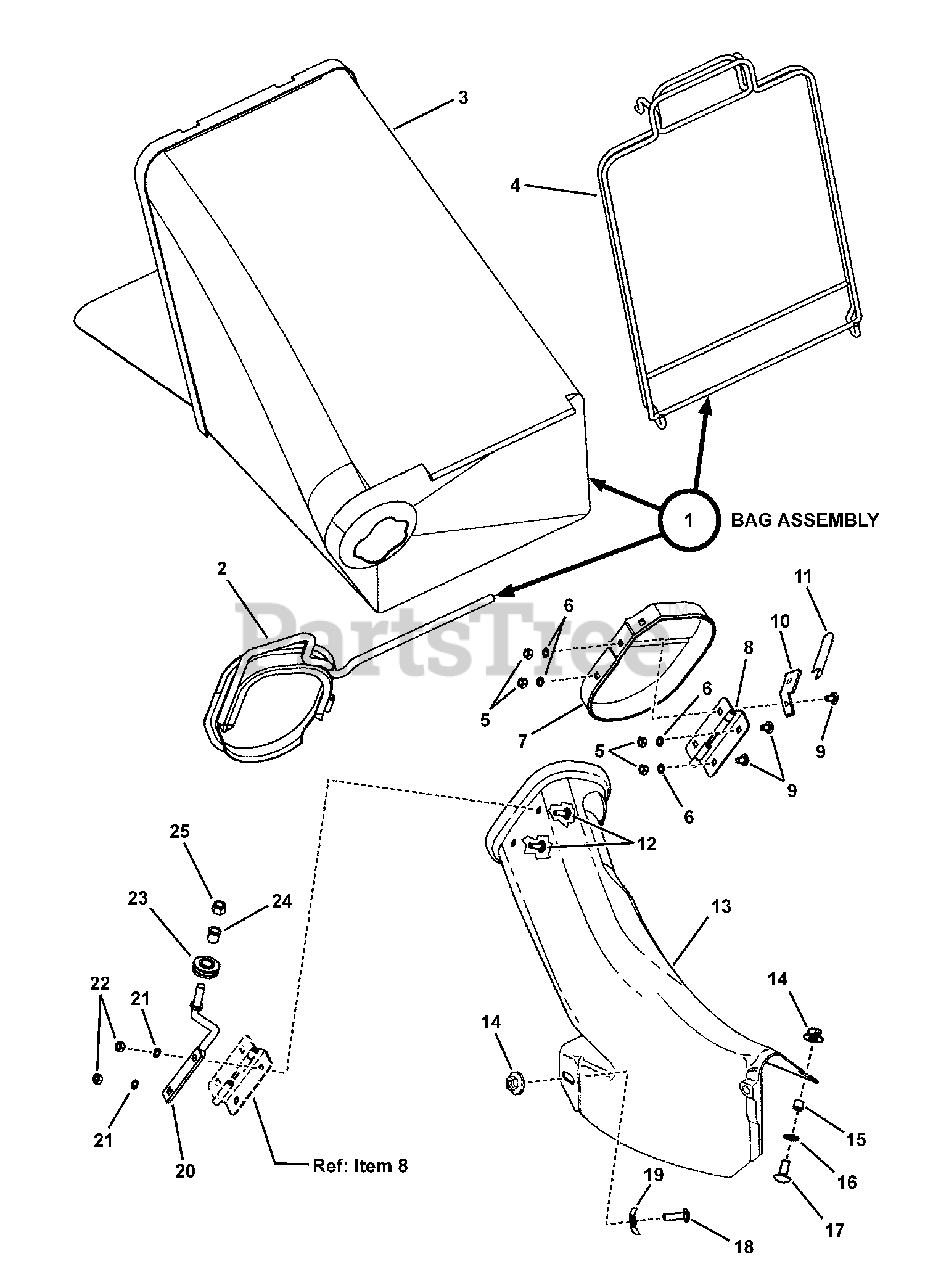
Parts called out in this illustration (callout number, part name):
1	BAG ASSEMBLY (Door)
2	CONNECTOR, Bag
3	GRASS BAG (Door w/silver letters)
4	ASSEMBLY, Bag Wire (12") 21S
5	NUT, 1/4-20 Hex
6	WASHER, 1/4" Internal Tooth Lock
7	COVER, Bag Adapter
8	HINGE, Chute Cover
9	BOLT, 1/4-20 x 5/8" Flat Head Square Neck, GR 5
10	STOP, Cover
11	TRIM, Moulding
12	BOLT, 1/4-20 x 3/4" Short Square Neck Carriage, GR 5
13	ADAPTER, Bag 21
14	NUT, 5/16-18 Large Flange Hex Center Lock
15	SPACER, .316 x .375 x .300/.310
16	BOLT RETAINER, 5/16- Black
17	BOLT, 5/16-18 x 3/4" Short Square Neck Carriage, GR 5
18	SCREW, 5/16-18 x 5/8" Cross Recess Pan Head
19	NUT, 5/16-18 Speed
20	ROD, Rope Pulley
21	LOCKWASHER, 1/4" Spring
22	NUT, 1/4-20 Hex Jam, GR 5 or B
23	PULLEY, Nylon
24	BUSHING, Flange, .381 x .625 x .62
25	NUT, 3/8-16 Hex Nyloc
